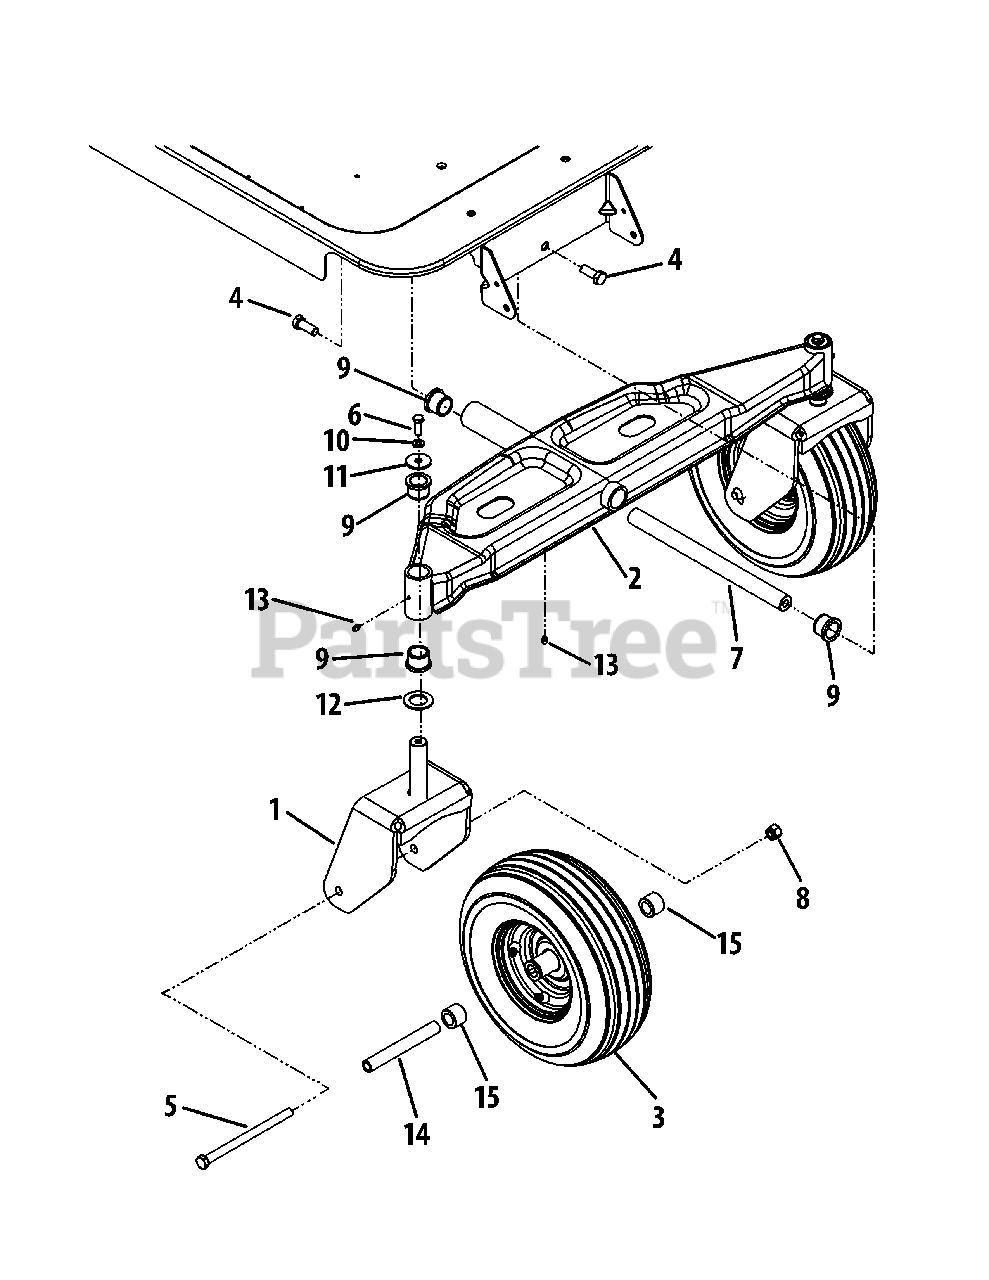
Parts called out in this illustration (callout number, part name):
1	Castor Wheel Bracket
2	Front Pivot Axle
3	Wheel Assembly, 13 x 5-6
4	Hex Lock Screw, 1/2-13 x 1.25
5	Hex Cap Screw, 1/2-20 x 7.25
6	Hex Cap Screw, 3/8-16 x 1.0
7	Axle Shaft
8	Hex Insert Lock Nut, 1/2-13
9	Flange Bearing, 1.0 x 1.246
10	Lock Washer, 3/8
11	Flat Washer, .39 x 1.5 x .134
12	Flat Washer, 1.0 x 1.75 x .10
13	Lube Fitting, 3/16 Drive
14	Spacer, .51 x .75 x 5.825
15	Hub, .76 x 1.23 x .92
